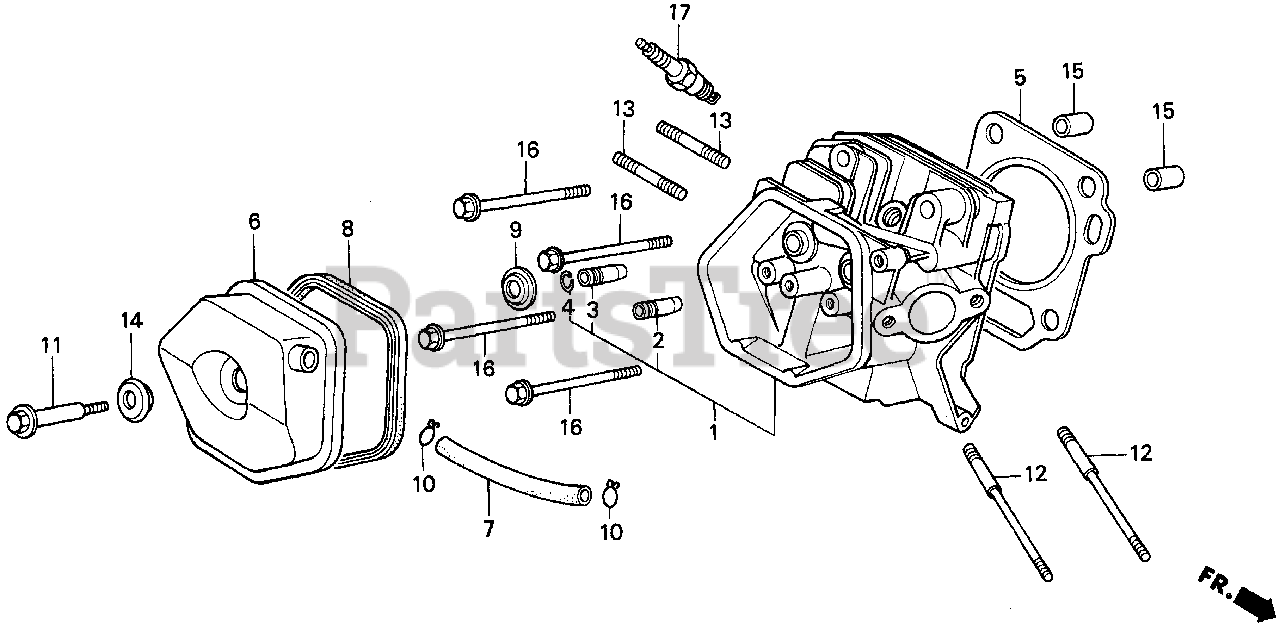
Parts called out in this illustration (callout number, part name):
1	CYLINDER HEAD
2	GUIDE, VALVE (OS)
3	GUIDE, EX. VALVE (OS)
4	CLIP, VALVE GUIDE
5	GASKET, CYLINDER HEAD
6	COVER, HEAD
7	BULK HOSE, VACUUM (11X1000) (11X105)
8	GASKET, CYLINDER HEAD COVER
9	SEAT, VALVE SPRING
11	BOLT, HEAD COVER
12	BOLT, STUD (8X123)
13	BOLT, STUD
13	BOLT 2, STUD (8X32)
14	WASHER, HEAD COVER
15	PIN A, DOWEL (12X20)
16	BOLT, FLANGE (10X80)
17	SPARK PLUG (BPR5ES) (NGK)
17	SPARK PLUG (W16EPR-U) (DENSO)
17	SPARK PLUG (BPR6ES) (NGK)
17	SPARK PLUG (W20EPR-U) (DENSO)
